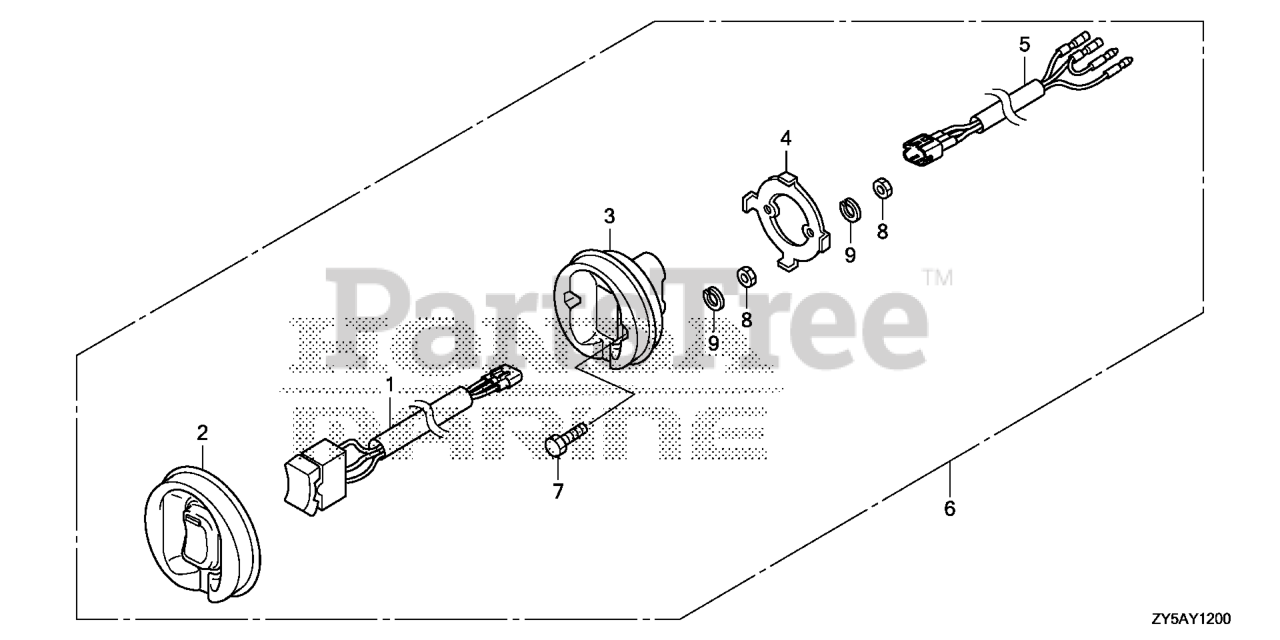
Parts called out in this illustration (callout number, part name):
1	SWITCH ASSY., TROLLING CONTROL (ENGINE NO.)
2	RUBBER, TROLLING CONTROL SWITCH PANEL (ENGINE NO.)
3	BODY, TROLLING CONTROL SWITCH PANEL (ENGINE NO.)
4	BRACKET, TROLLING CONTROL SWITCH PANEL (ENGINE NO.)
5	HARNESS, TROLLING CONTROL SWITCH PANEL (ENGINE NO.)
6	PANEL ASSY., TROLLING CONTROL (ENGINE NO.)
7	BOLT, HEX. (4X20) (ENGINE NO.)
8	NUT, HEX. (4MM) (ENGINE NO.) (NOT AVAILABLE)
9	WASHER, SPRING (4MM) (ENGINE NO.)
